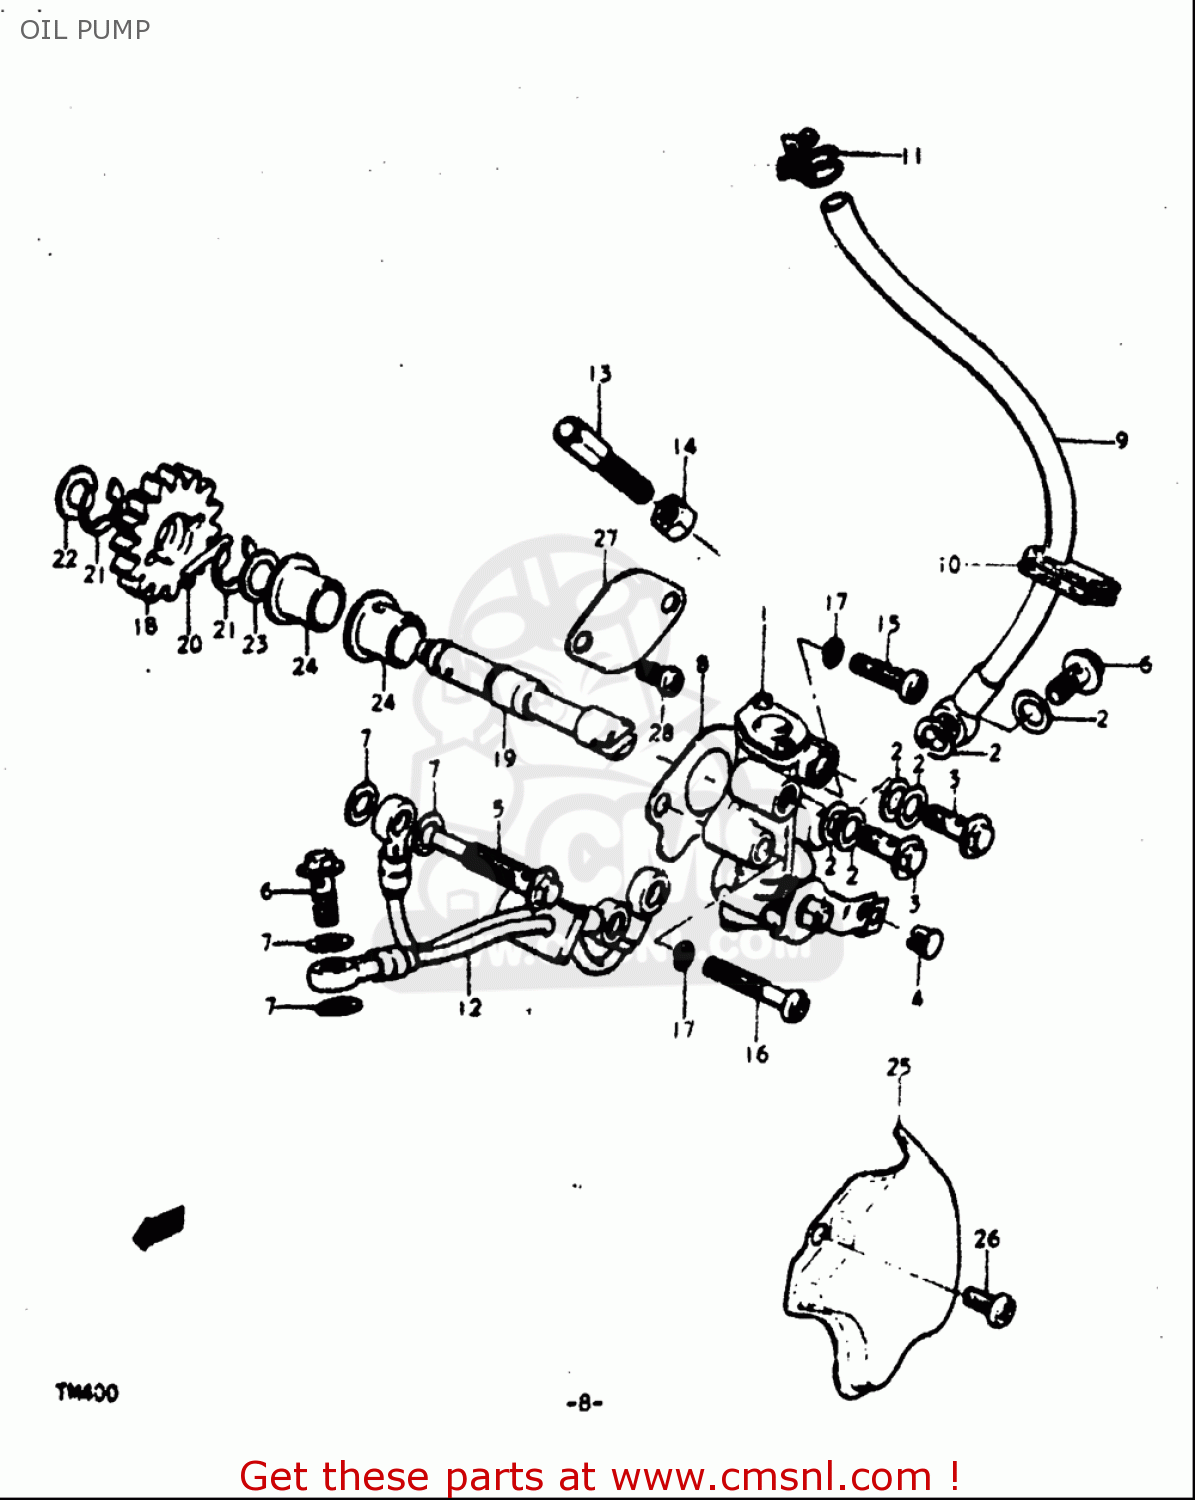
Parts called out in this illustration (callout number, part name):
2	GASKET(6.2X11X1).2 (NAS)
3	UNION BOLT
4	TERMINAL,CABLE
5	UNION
6	UNION BOLT
8	GASKET,OIL PUMP (NAS)
9	HOSE,INLET
10	GROMMET
11	CLIP
13	BOLT
14	NUT
15	SCREW
16	SCREW
17	WASHER,LOCK
20	ROLLER(4X23.8)
21	E RING
22	SHIM(8X16X1)
23	SHIM(10X16X1)
26	SCREW
27	CAP,OIL PUMP DRIVE SHAFT
28	SCREW
